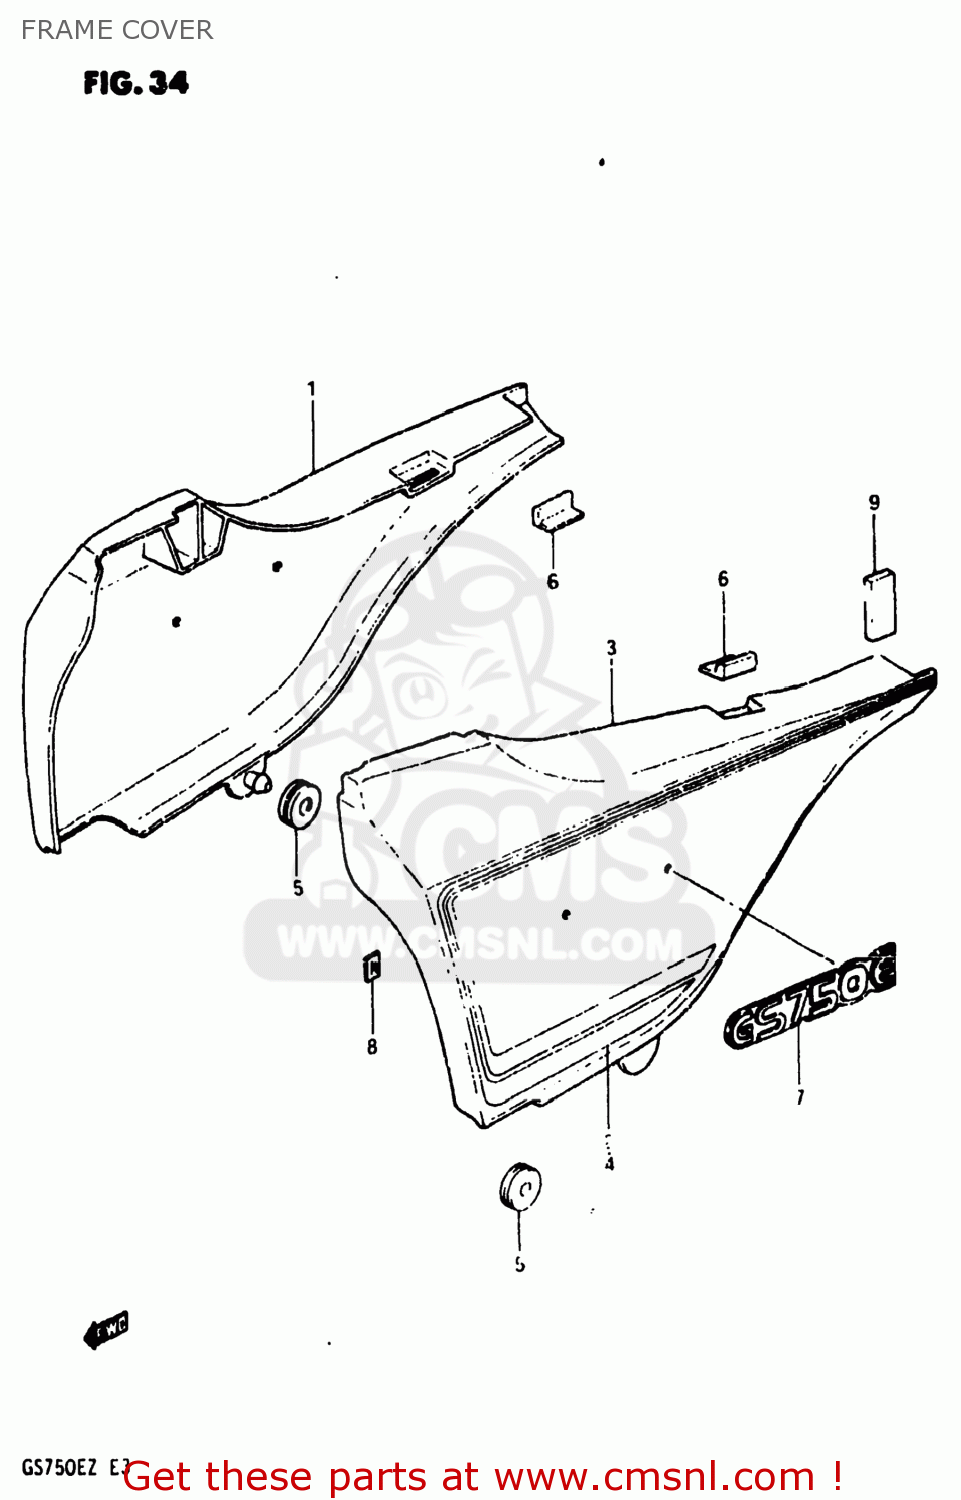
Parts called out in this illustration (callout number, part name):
1	COVER,FRAME,R
2	TAPE SET,FRAME COVER
3	COVER,FRAME,LEFT
4	TAPE SET,FRAME COVER
5	CUSHION
6	CUSHION,FRAME COVER
7	EMBLEM,FRAME COVER
8	NUT
9	RUBBER,FRAME COVER
